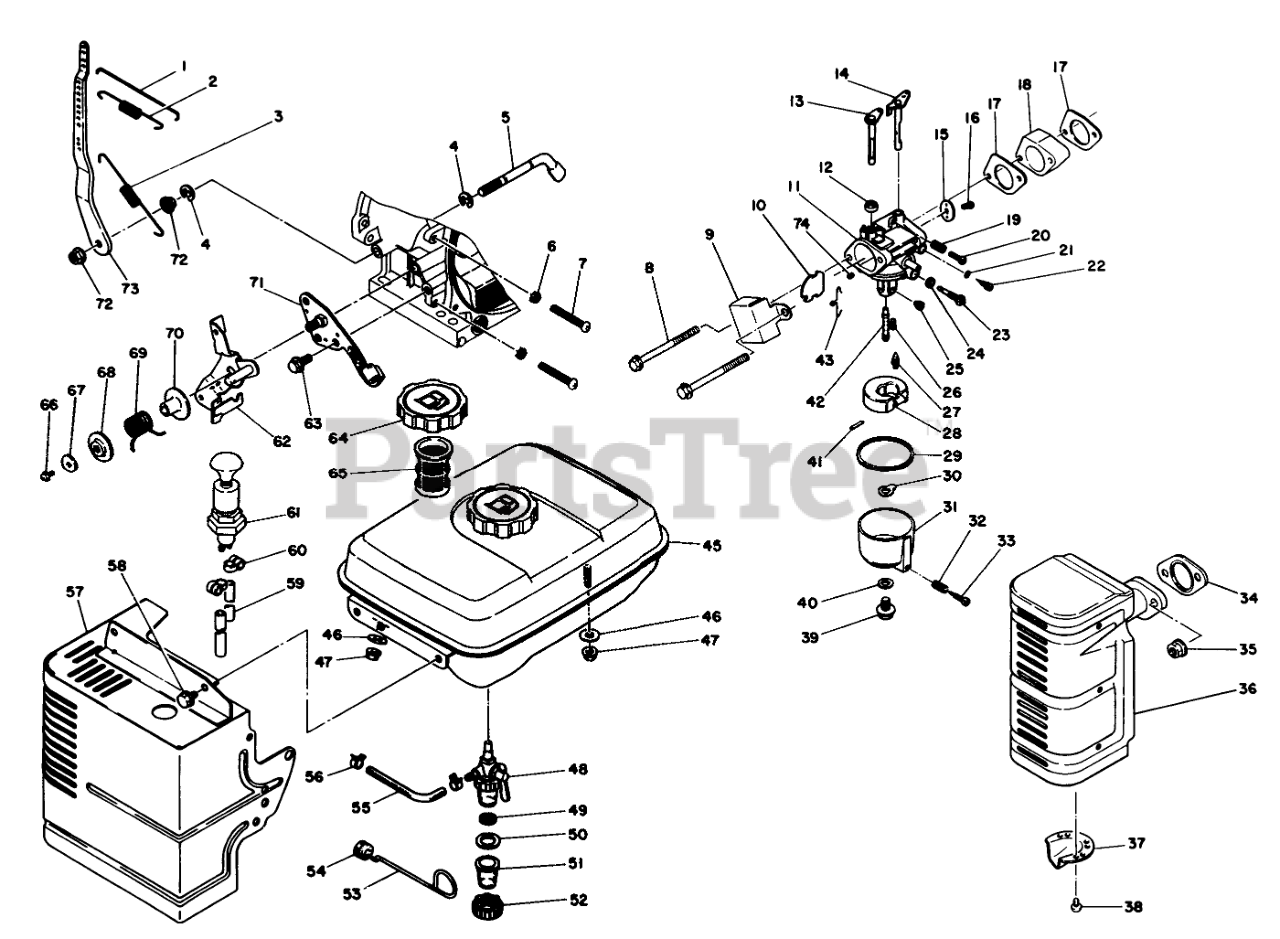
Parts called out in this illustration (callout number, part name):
1	GOV.ROD
2	SPRING-ROD
3	GOV.SPRING
4	SNAP RING
5	GOV SHAFT
7	SCREW
9	Cover
10	CHOKE VALVE
11	Carburetor Assembly (Incl. Ref . #10-16 & 19-43)
13	CHOKE SHAFT
14	THROTTLE SHAFT
15	THROTTLE VALVE
16	SCREW
17	CARB GASKET
18	INSULATOR
19	SPRING
20	SCREW
21	Seal-O-Ring
22	Valve-Needle (Incl. Ref. #21)
23	SLOW JET
24	Gasket
25	MAIN JET
26	SCREW
27	VALVE
28	FLOAT
29	GASKET
30	GASKET
31	Bowl-Float (Incl. Ref. #32 & 38)
32	SPRING
33	SCREW
34	GASKET
36	Muffler Assembly (Incl. Ref. #37 & 38)
37	TAIL PIPE
38	SCREW
40	GASKET
41	FLOAT PIN
42	MAIN NOZZLE
45	Fuel Tank Assembly (Incl. Ref. #64 & 65)
46	GASKET
47	Nut-Flange
48	Petcock-Fuel (Incl. Ref. #49-52)
49	SCREEN
50	GASKET
53	CHOKE ROD
54	GROMMET
57	Cover-Engine
60	CLAMP
61	Fuel Pump Assembly
62	CONTROL LEVER
64	FUEL TANK CAP
65	FUEL FILTER
66	SCREW & WASHER
67	WASHER
69	SPRING
71	CONTROL PANEL
73	GOV.LEVER
74	BREATHER
